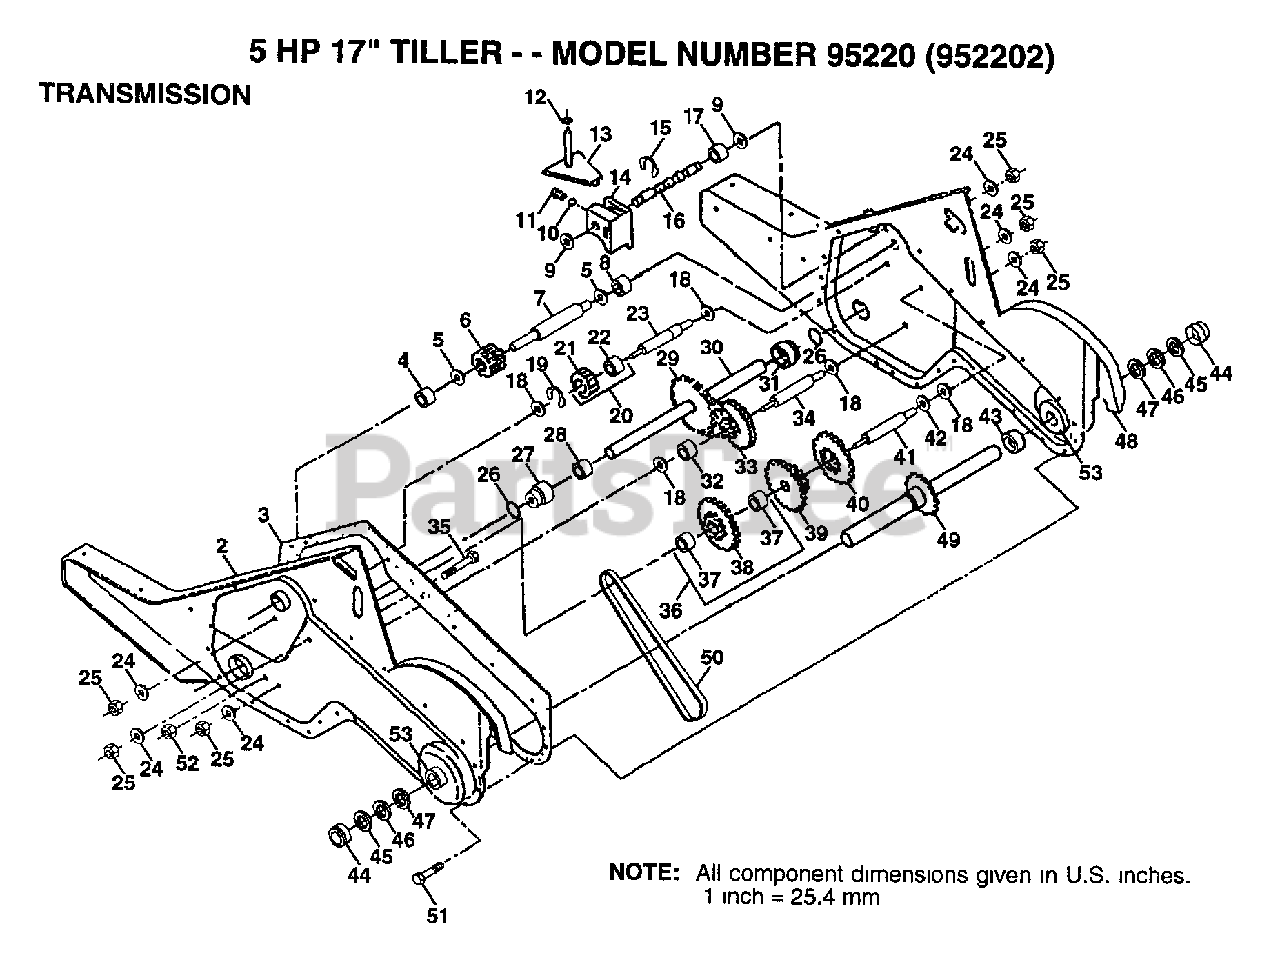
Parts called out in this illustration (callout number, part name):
2	GEARCASE, L.H.
3	GASKET TI
4	NEEDLE BRNG LT
5	"T, BEARING"
6	PINION-INPUT CRT
7	SHAFT-INPUT CRT
8	"TI, BEARING"
9	WASHER SEAL CRT
11	SPRING-SHIFT CRT
12	O-RING TI
13	ARM ASSY CRT
14	SHIFT FORK TI
15	KLIP RING
16	SHAFT SHIFT CRT
17	SPACER SPLIT CRT
18	WASHER
19	KLIP RING
20	GEAR ASSY CRT
21	GEAR-REV IDLR CRT
22	NEEDLE BEARING TI
23	SHAFT CRT
24	LOCKWASHER
25	NUT.ASF.HEX.7/16
26	O RING CRT
27	"CRT, BEARING"
28	BUSHING TI
29	CHAIN CRT
32	SPACER TI
33	SPRCKT 8 GEAR CRT
34	SHFT 2ND RED. CRT
35	SCRW WHIZ LOK CRT
36	SPROCKET ASM.
37	BEARING
39	GEAR TI
40	GEAR TI
41	REDUCTION SHFT TI
42	BRNG RACE
43	SPACER TI
44	CUP.FORMED.
45	RING SPIRAL CRT
49	TINE SHAFT
50	CHAIN.50 LINK TI
51	SCREW CRT
52	NUT.HEX.5/16-18
